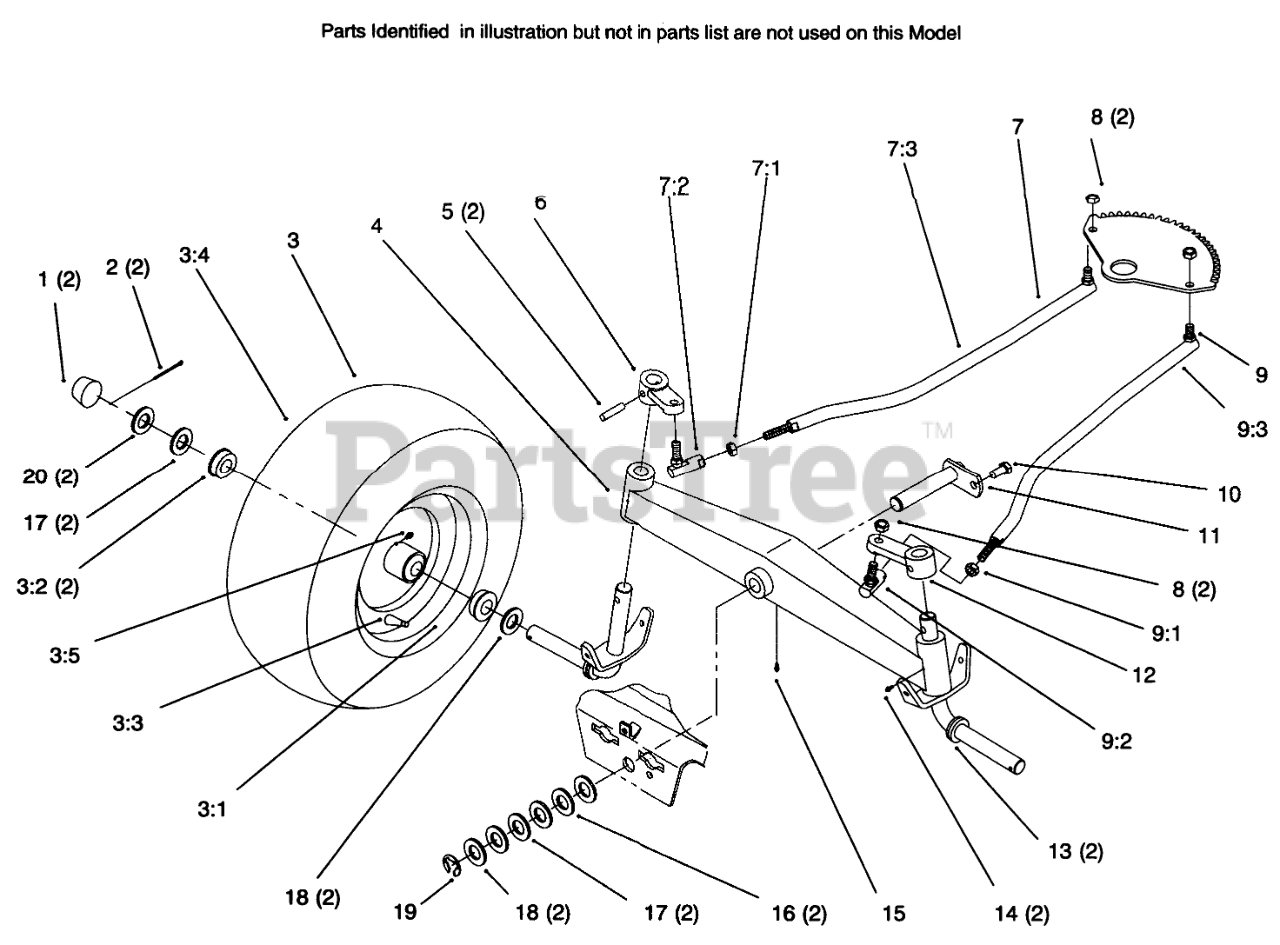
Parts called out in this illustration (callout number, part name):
1	CAP-HUB
2	PIN-COTTER
3	ASM-Wheel & Tire
3:1	Wheel ASM
3:2	BEARING-WHEEL
3:3	VALVE
3:4	Tire (16 x 6.5-8) 2-Ply -2 Wheel Axel
4	AXLE-FRONT
6	Arm-Front Spindle
7	LINKAGE-STEERING, RH
7:1	Nut-Hex Jam
7:2	BALL-JOINT
7:3	Ball Link ASM
9	LINKAGE-STEERING, LH
9:1	Nut-Hex Jam
9:2	BALL-JOINT
9:3	Ball Link ASM
10	SCREW-HWH, TAPTITE
11	PIN-AXLE
12	Arm-Front Spindle
13	SPINDLE
14	FITTING-GREASE
15	FITTING-LUBE, 45 DEG
16	Washer
17	WASHER
18	WASHER-SHIM
19	E-RING
20	WASHER-PLAIN
